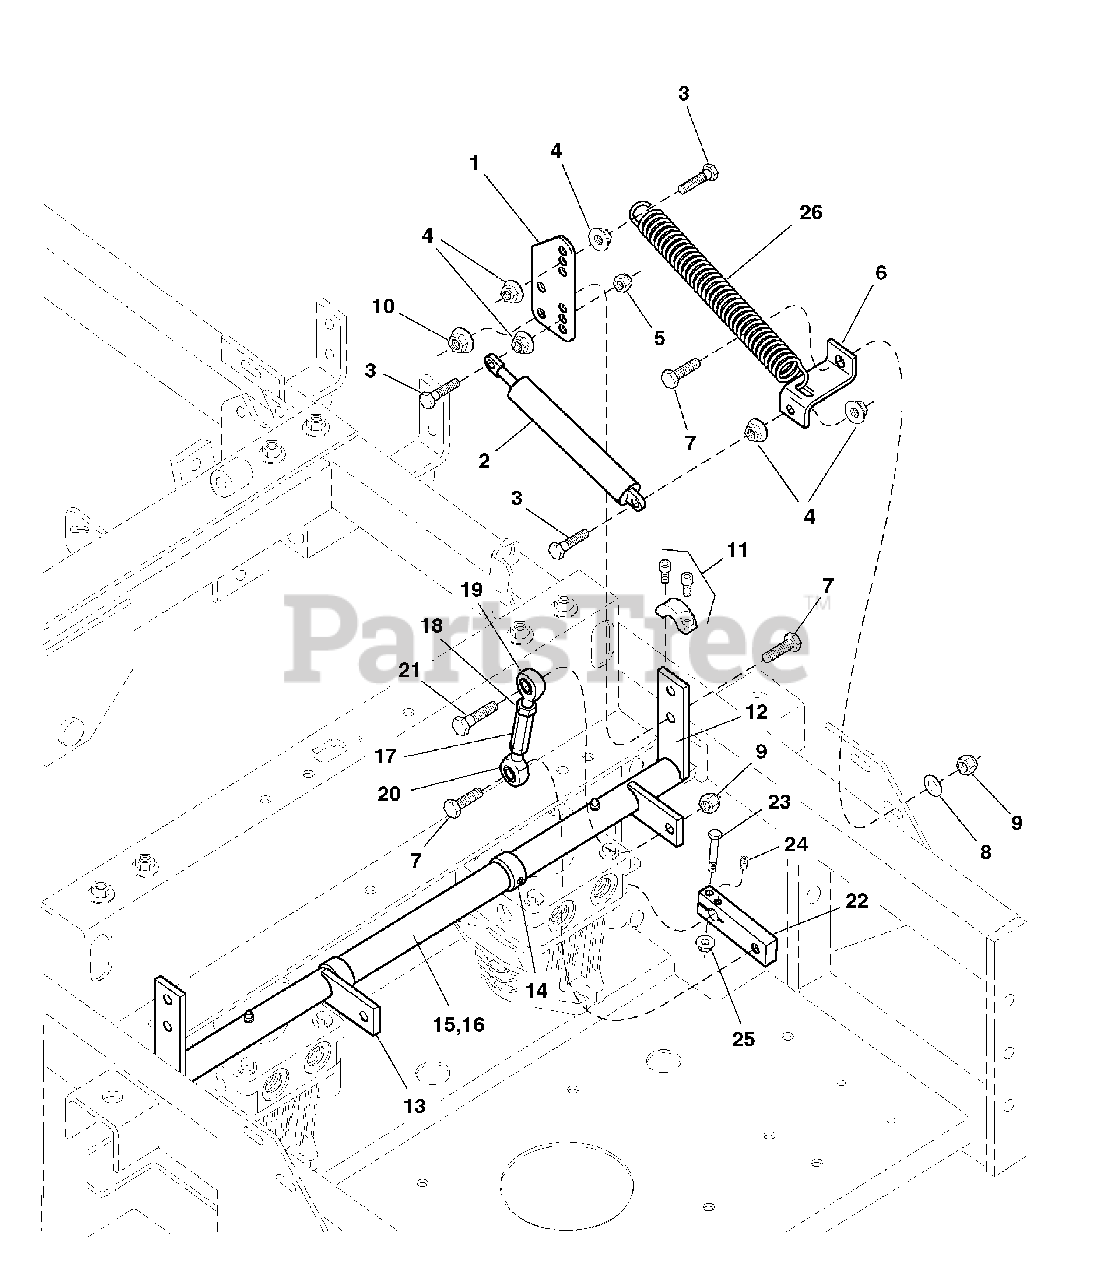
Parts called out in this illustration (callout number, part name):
1	DAMPENER MOUNT PLATE
3	CAPSCREW, Hex Hd, 5/16-18 x 1-1/4
4	NUT, Hex, Serrated Flange, 5/16-18
5	NUT, Hex, Nylon Lock, 5/16-18
6	DAMPENER MOUNT, Rear
7	CAPSCREW, Hex Hd, 3/8-16 x 1
8	WASHER, 3/8
9	NUT, Hex, Nylon Lock, 3/8-16
10	NUT, Hex, Serrated Flange, 3/8-16
11	COLLAR, 3/4 Double Split
12	HYDRO CONTROL LEVER-RH
13	HYDRO CONTROL LEVER-LH
14	COLLAR, 3/4 Set
15	SHAFT, Control Pivot (hidden by cover)
16	COVER, Control Shaft
17	HEX ROD, Short
18	NUT, Hex, 3/8-24
19	BALL JOINT, 3/8
20	BALL JOINT, 3/8, LH
21	CAPSCREW, Hex Hd, 3/8-16 x 1-1/4
22	PUMP CONTROL ARM
23	CAPSCREW, Hex Hd, 1/4-20 x 1-1/4
24	SET SCREW, Cone, 1/4-20 x 3/8
25	NUT, Hex, Serrated Flange, 1/4-20
26	SPRING, Extension
